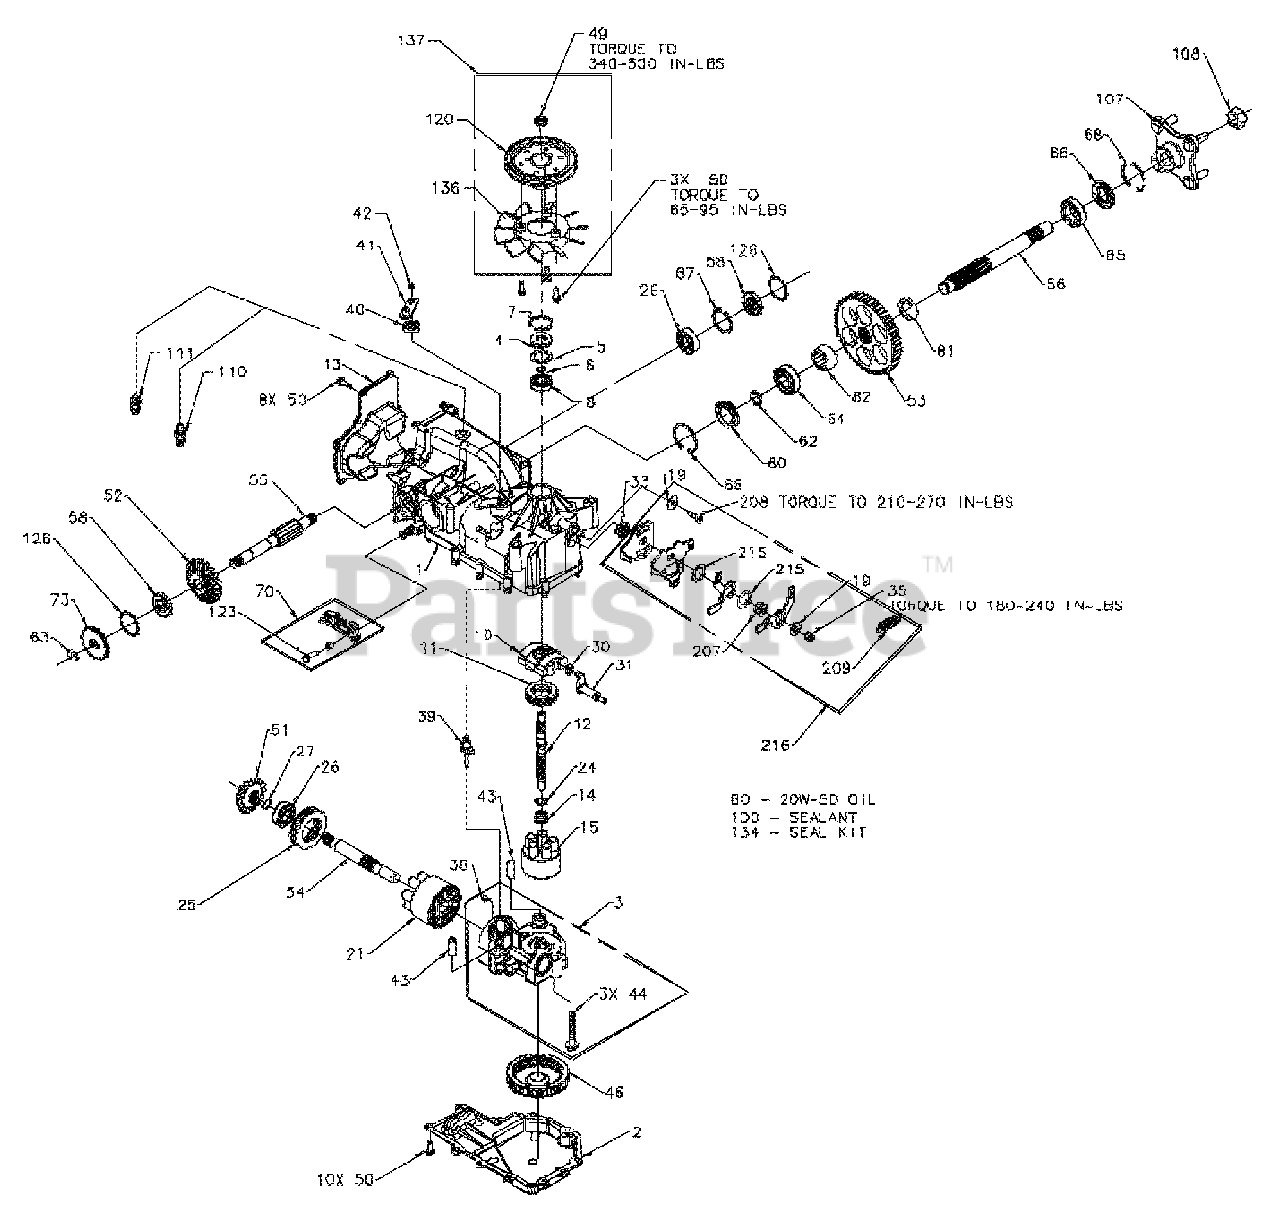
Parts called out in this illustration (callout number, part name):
1	Kit, Housing - Main
3	KIT, C-SECTION
4	ACTUATOR, BYPASS
5	WASHER .98X1.37X.04
6	RING, WIRE RETAINING
7	RING. RETAINING
8	BEARING, SHAFT BALL
10	SWASHPLATE. VARIABLE
11	BEARING. THRUST 30 X 52 X 13
12	SHAFT, INPUT
13	COVER, END IZT
14	SPRING. BLOCK
18	KIT, 10 CC BLOCK
19	WASHER
21	21 cc Cylinder Block Assembly
24	WASHER. THRUST .59 X .79 X .04
25	BRG, THRUST BALL 42X68X16
26	BRG, BALL 17X40X12
27	RING, RET WIRE .561 ID
30	GUIDE. SLOT
31	ARM. TRUNNION TAPERED SQUARE
33	SWASHPLATE. VARIABLE
35	NUT, HEX 5/16-24 NYLON
38	KIT, BYPASS PLATE
39	ACTUATOR, BYPASS
40	SEAL, LIP
41	ARM. BYPASS
42	RING. RETAINING1
43	PIN-HOLLOW .39X.5X1.
44	HFHCS 3/8-24X2.5 (PATCH)
46	FILTER
49	Nut, Hex Lock .50-20 with Nylon Insert
50	HFHCS 1/4-20X.75
51	GEAR, BEVEL 14T
52	GEAR, BEVEL 19T
53	GEAR, SPUR 53T
54	SHAFT, MOTOR
55	SHAFT, BRAKE
56	AXLE, 1.0X12.3
57	SEAL, LIP 17X40X7
60	PLUG, SEAL 1.86
62	RING, RET .75 EXT
63	RING, RET .440 EXT
64	BRG, BALL 25X47X12
65	BRG, BALL 25X47X12
66	SEAL, LIP 25X47X7
67	RING, RET 1.56 INT
68	RING, RET 1.87 INT
70	BRAKE ARM,RH IZT
73	Brake Disc
80	20W - 50 Oil
81	Axle Bushing
82	Axle Bushing
100	SEALANT TUBE 10.1OZ.
107	Hub Assembly
110	FTG-STR .50 O-RING
111	CAP-VENT .50
120	Kit, Seal
123	HFHCS 1/4-20X.875
126	RING, RET 1.43"
134	KIT, SEAL
137	Kit, Fan /Pulley
207	Spacer, RTN
208	SHCS 5/16-24X.75
209	Spring, Extension
215	WASHER
216	KIT, RTN SCISSOR
